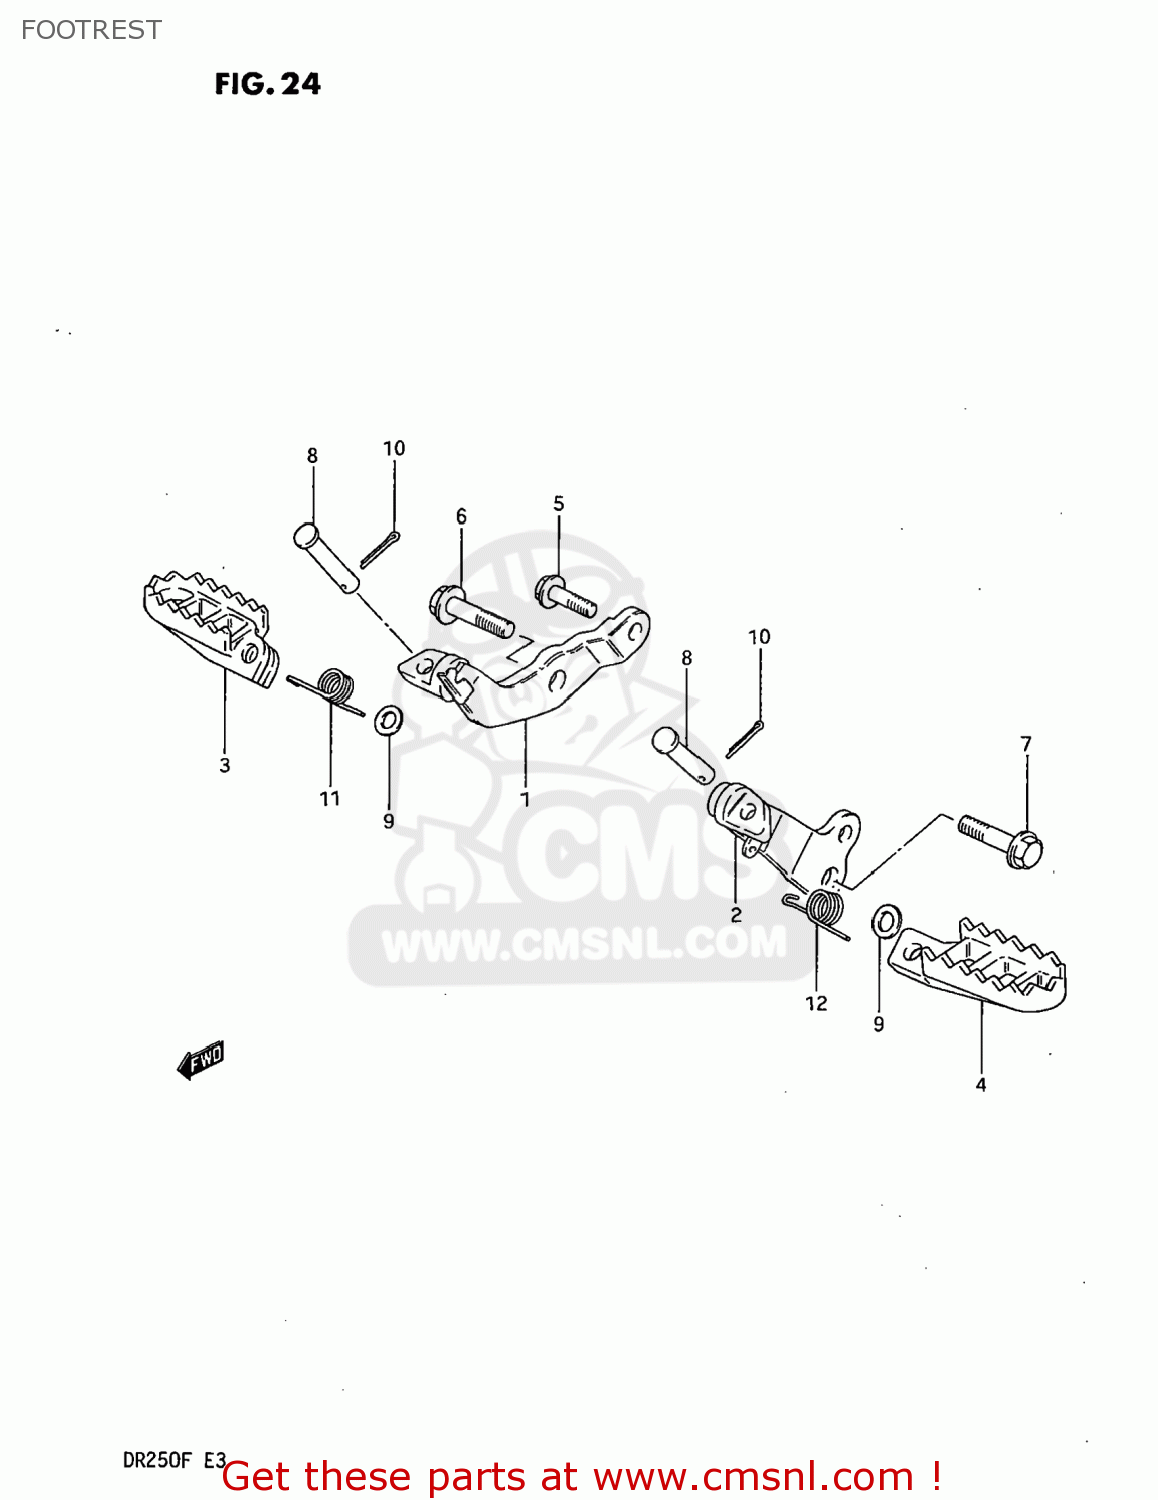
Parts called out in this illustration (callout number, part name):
1	BAR,FRONT FOOTREST
2	BAR,FRONT FOOTREST,LEFT
3	FOOTREST
4	FOOTREST
5	BOLT,LOWER
6	BOLT, RH
7	BOLT
8	PIN
9	WASHER
10	PIN 20X20
11	SPRING
12	SPRING
